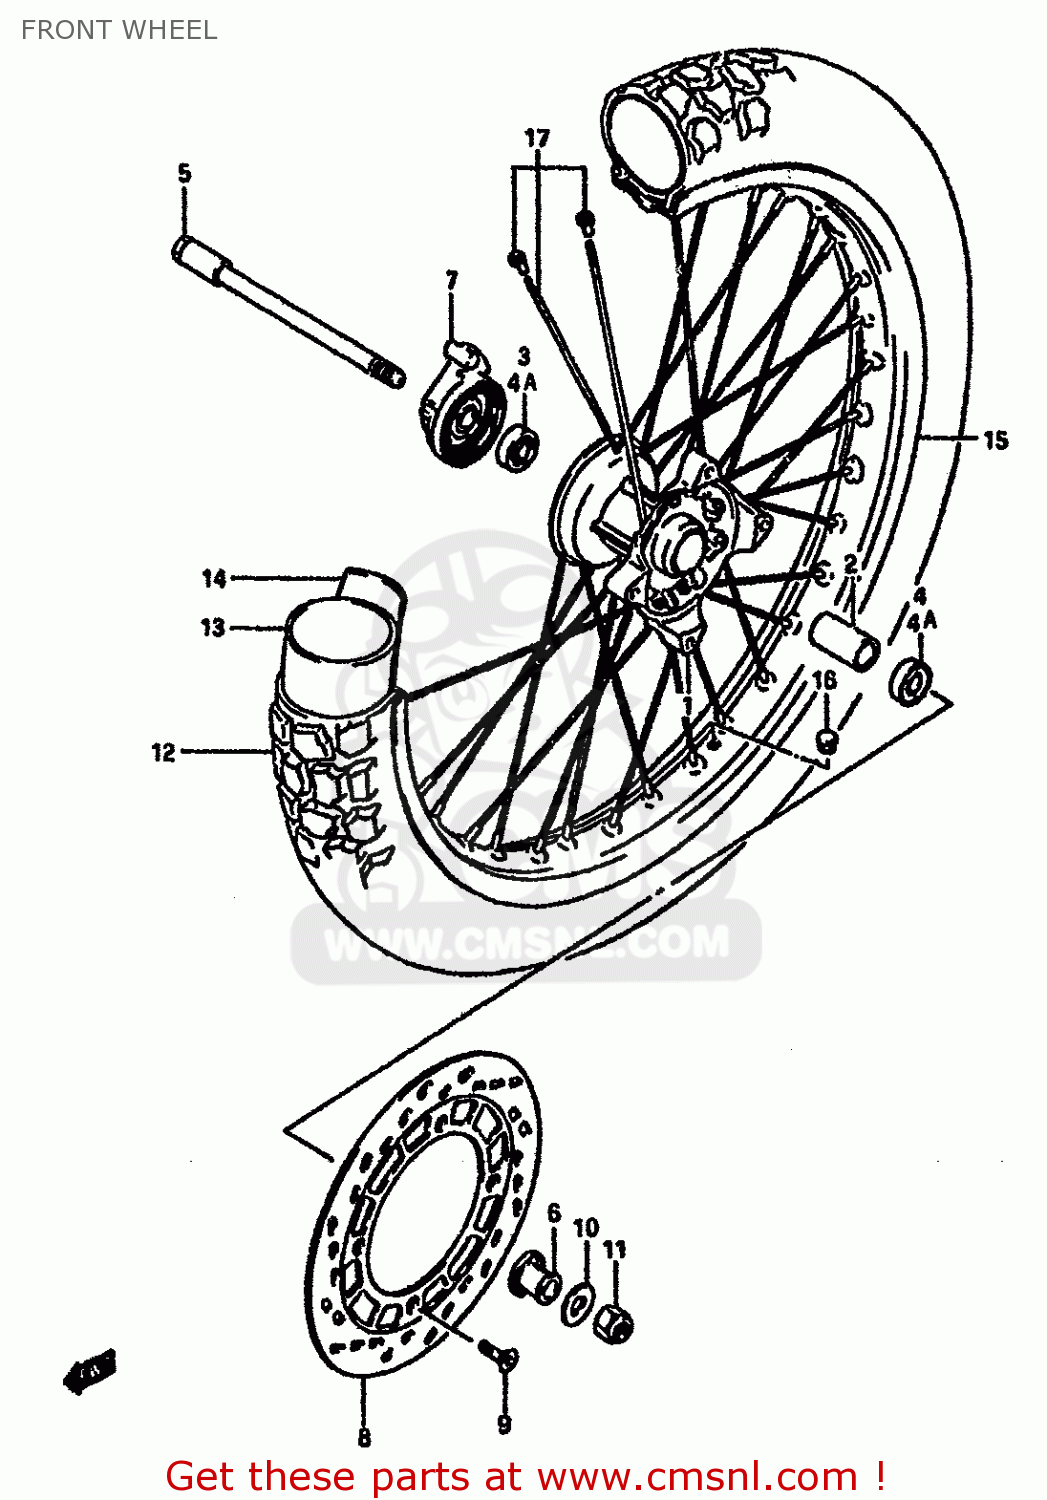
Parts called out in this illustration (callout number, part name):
1	HUB,FRONT
2	SPACER(15.3X21.7X56)
3	BEARING
4	BEARING
4A	BEARING
5	AXLE,FRONT
6	SPACER,FRONT AXLE,LEFT
7	BOX ASSEMBLY,SPEEDOMETER GEAR
8	DISC,FR BRAKE
9	BOLT,BRAKE DISC
10	WASHER
11	NUT
12	TIRE 100/80-21
13	TUBE
14	PROTECTOR,WHEEL,INNER
15	RIM,FRONT WHEEL
16	CAP(OD:12)
17	SPOKE SET,FRONT
